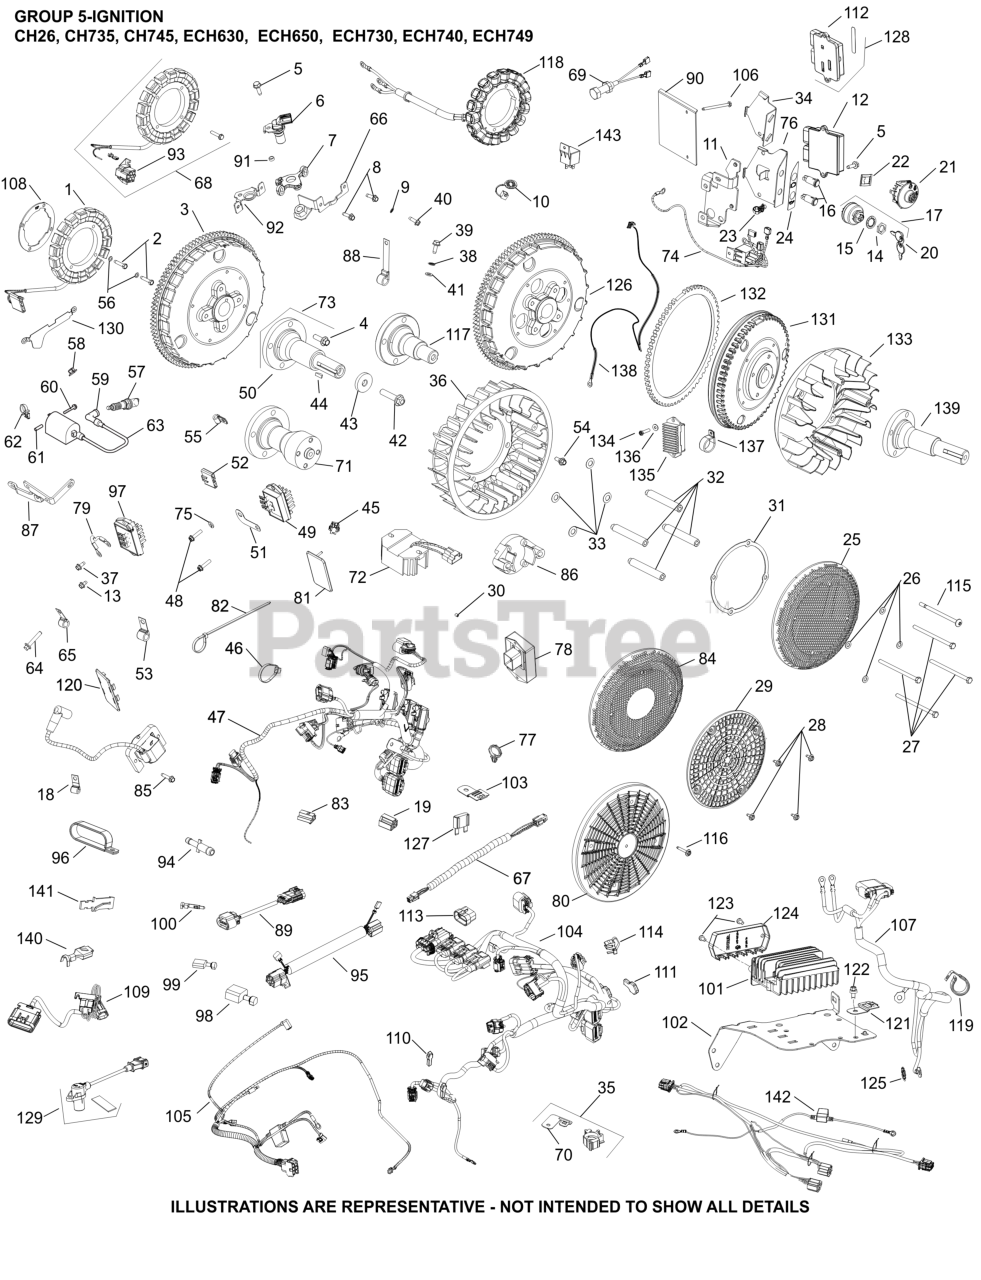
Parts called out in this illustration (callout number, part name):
1	KIT, 15 / 20 AMP STATOR
2	SCREW, THREAD FORMING
3	FLYWHEEL, ASSEMBLY
6	SENSOR, SPEED
8	SCREW, THREAD FORMING
9	WASHER, INT TOOTH LOCK #10
10	CAP, CONNECTOR
11	BRACKET, ECU
14	NUT, KEY SWITCH
15	WASHER, INTERNAL TOOTH
16	LIGHT, INDICATOR
17	KEY ASSEMBLY SWITCH-USE 25 099 37-S
20	KEY, SET OF 2
23	TIE, WIRE
24	DECAL, WARNING LIGHT
25	KIT GRASS SCREEN
30	SCREW, FLG M10X1.5X45-USE 25 086 361-S
36	FAN-USE 24 755 253-S
37	SCREW, THREAD FORMING
38	WASHER, INT TOOTH LOCK 1/4"
41	WASHER, FLAT 1/4" (O.D. 1/2")
43	WASHER, FLAT 13/32"
44	KEY, 3/16" X 5/8"
47	HARNESS, WIRING ASSEMBLY
48	SCREW, HEX FLANGE HI-LO
52	CONNECTOR
54	BOLT, SHOULDER
57	SPARK PLUG, RFI
63	COIL, IGNITION - EFI (RFI/EMC)
64	SCREW, FLG (BLACK) M6X1.0X34
76	BRACKET, WARNING LIGHT
77	RETAINER, WIRE HARNESS
80	SCREEN, GRASS
92	BRACKET, SENSOR
97	REGULATOR, RECT (20-30AMP, FW W/OVP)
116	SCREW, FLG SEMS M4x.7x25
NI	MODULE, ECU ECH730
